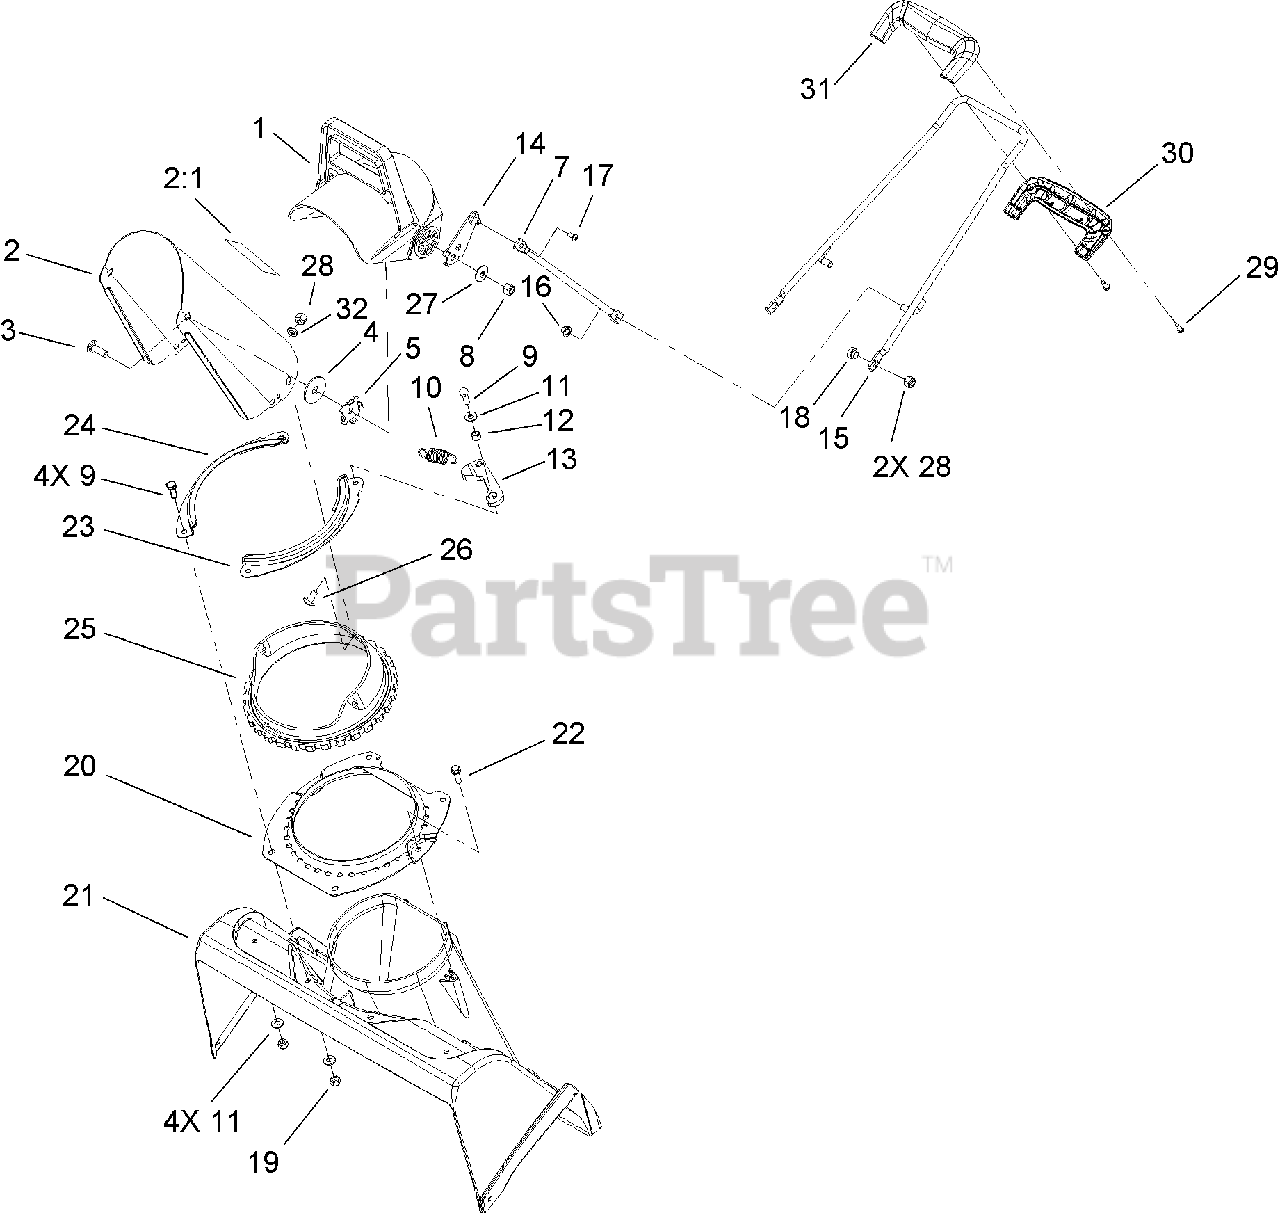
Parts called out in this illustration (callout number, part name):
1	CHUTE-DEFLECTOR
2	CHUTE ASM
2:1	DECAL-DANGER
3	SCREW-CARR
4	WASHER-RUBBER
5	PLATE-FRICTION
7	ROD-SUPPORT
8	NUT-LOCK, NI
9	SCREW-HH
10	SPRING-EXTENSION
11	WASHER-FLAT
12	SPACER-BLADE, ROTOR
14	PIVOT ARM ASM
15	CHUTE HANDLE ASM
16	PUSHNUT-CAP, WASHER
17	SCREW-PPH
18	SPACER-FLANGED
19	NUT-LOCK, NI
20	RING-SUPPORT, CHUTE
21	HOUSING-ROTOR, UPPER
22	SCREW-HWH
23	RETAINER-CHUTE, LH
24	RETAINER-CHUTE, RH
25	RING-GEAR, CHUTE
26	SCREW-CARR
27	WASHER-BELLEVILLE
28	NUT-LOCK, NI
29	SCREW-PPH
30	HANDLE-BOTTOM
31	HANDLE-TOP
32	WASHER-FLAT
